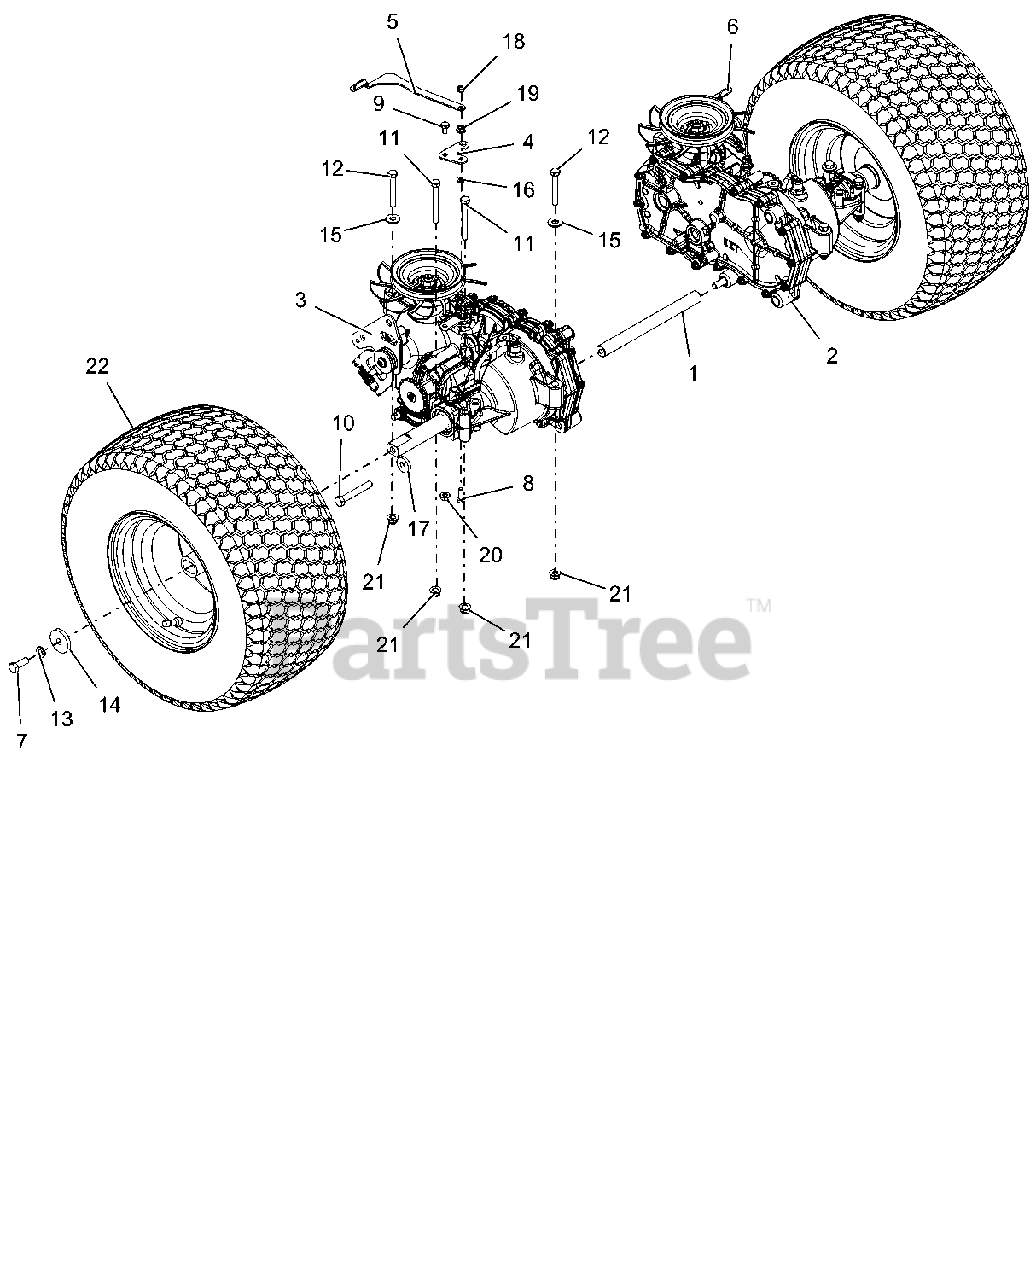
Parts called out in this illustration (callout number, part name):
1	ROD, TRANSAXLE BRACE
2	TRANSAXLE,LH EZT D-SHFT SHORT
3	TRANSAXLE,RH EZT D-SHFT SHORT
4	BRKT, DUMP VALVE EXTENSION
5	BRKT, DUMP VALVE RH
6	BRKT, DUMP VALVE LH
7	BLT-HEX .38-16X1.0 GR8 YZ EP30
8	@BLT-HEX .25-20X.75 GR5 YWZC
9	@BLT-HEX .25-20X.50 GR5 YWZC
10	@BLT-HEX .38-16X2.50 GR5 YWZC
11	@BLT-HEX .31-18X2.75 GR5 YWZC
12	@BLT-HEX .31-18X2.25 GR5 YWZC
13	@WSHR-LK .38X.094 REG YWZC
14	WSHR,FLT STL.406X1.50X.245YWZC
15	@WSHR-FL-STL.38X.875X.083 YWZC
16	WSHR-FL-STL .265X.50X.087YWZC
17	WSHR-FL-STL .406X1.00X.188 YWZ
18	NUT-LK-CTR JAM .25-20 YWZC
19	@NUT-SPNLK-FLG .25-20 YWZC
20	@NUT-LK-TOP-FLG .25-20 YWZC
21	@NUT-LK-NYL-FLG .31-18 YWZC
22	ASM, WHL/TIRE 18X8.50-8 DHUB
